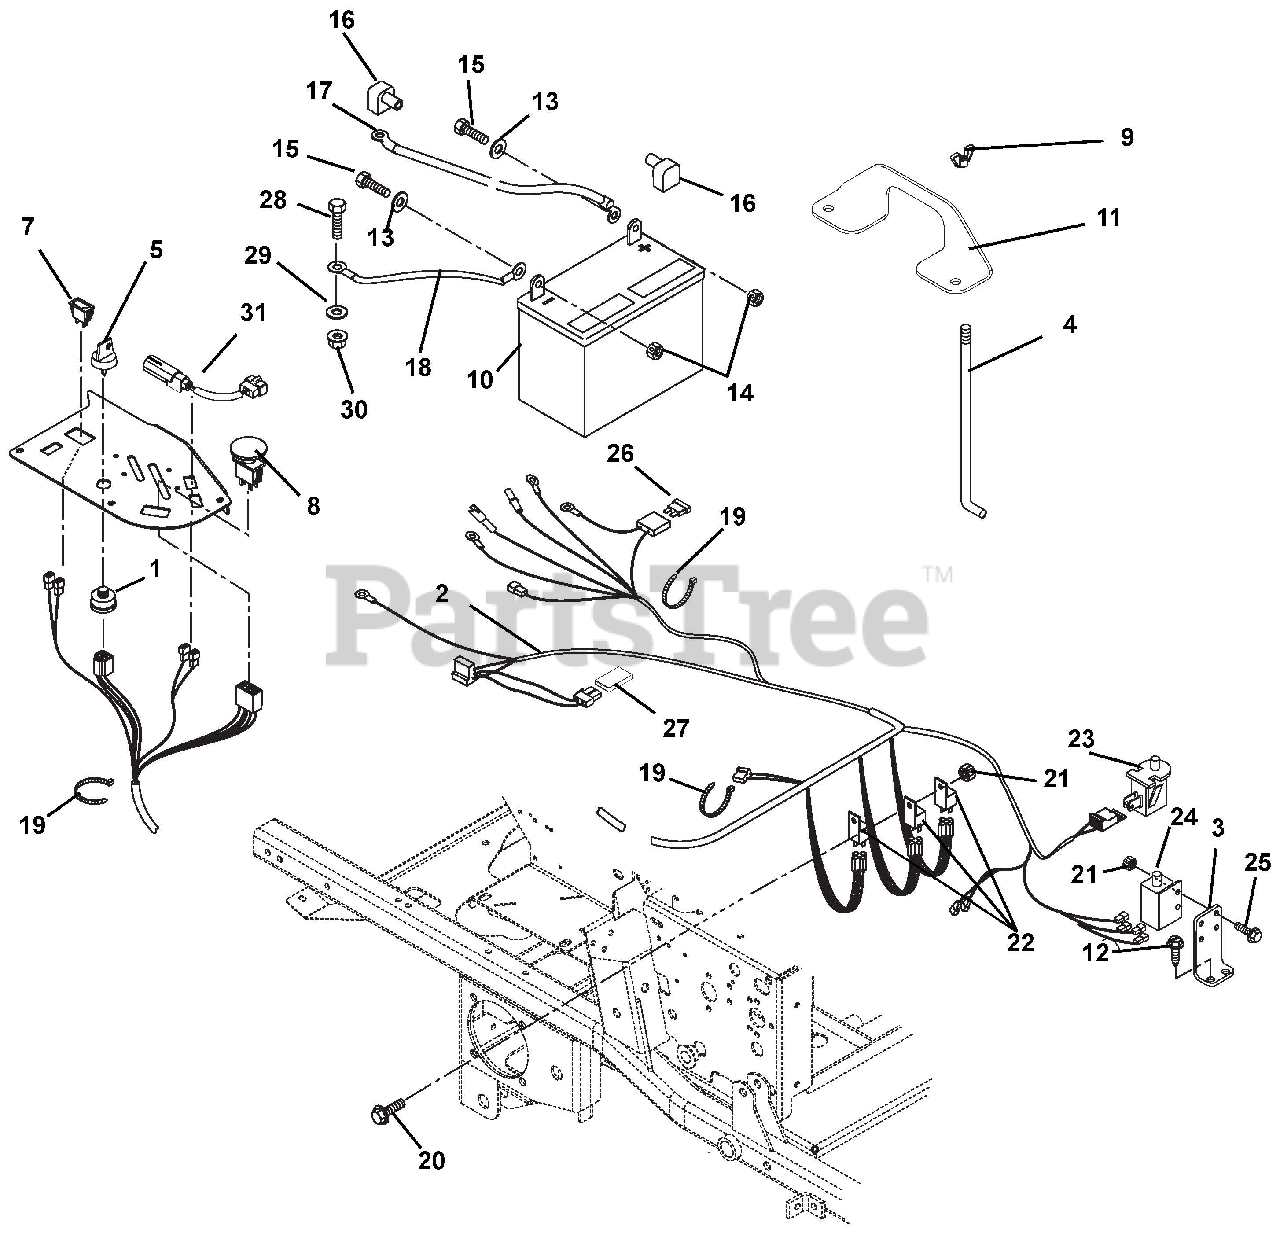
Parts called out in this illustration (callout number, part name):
1	Switch, Ignition
2	Harness, MZ Vertical A/C
2	Harness, MZ Vertical Liquid Cooled
3	Mount, Safety Switch
4	Rod, Battery Hold Down .25 x 6.62
5	Key, with Shield
6	Ignition Key Set
7	Hour Meter
8	Switch, PTO Clutch
9	Nut, Locking Wing .25-20
10	Battery, 12V
11	Hold Down, Battery
12	Screw, Tapping .25-20 x .50 Hex Washer Head
13	Washer, Flat-Steel .281 x .620 x .065
14	Nut, Locking Top Flange .25-20
15	Bolt, Hex .25-20 x .75 Grade 5
16	Battery Terminal Boot, Red
17	Starter Cable 13 in.
18	Ground Cable
19	Cable Tie
20	Screw, Machine 10-24 x .50 Hex Washer Head
21	Nut, Locking-Nylon 10-24 With Insert
22	Relay
23	Switch, Snap Mounting
24	Switch, Double Pole N.O./N.O.
25	Screw, Machine 10-24 x .75 Hex Washer Head
26	Fuse, 30 Amp
27	Diode, Connector Shell
28	Bolt, Hex .31-18 x .75 Grade 5
29	Washer, Flat Steel .344 x .688 x .065
30	Nut, Locking Top Flange .31-18
31	Light, Indicator
